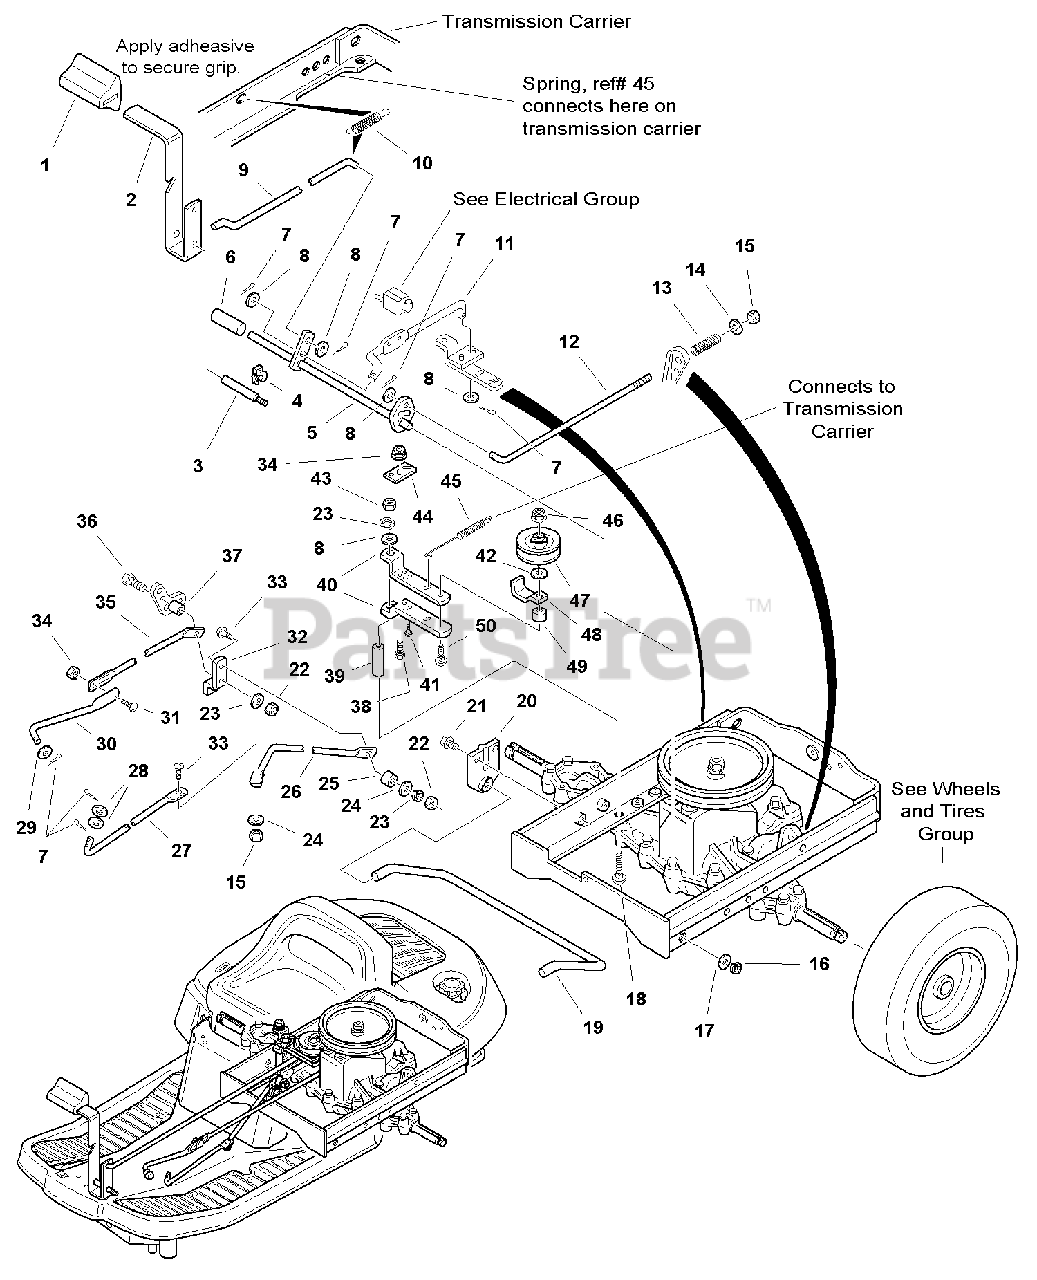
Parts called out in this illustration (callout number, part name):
1	PAD, Pedal
2	LEVER, Clutch
3	PIVOT, Brake
4	KLIP RING, 3/4
5	PIVOT SHAFT ASSEMBLY
7	COTTER PIN, 7/64 x 3/4
9	ROD, Clutch, Front
10	SPRING, Return
11	ROD, Clutch, Rear
13	SPRING, Compression
14	WASHER, 13/32 x 1-1/4 x 5/64
15	NUT, Hex, Lock, 5/16-18
16	KLIPRING, 1/2
17	WASHER, Plain
18	CARRIAGE BOLT, 5/15-18 x 2-3/4
19	TORSION BAR
20	BRACKET, Torsion Bar
21	CAPSCREW Taptite, 5/16-18 x 1/2
22	NUT, Hex Flange Lock, 5/16-18
23	LOCKWASHER, 5/16
24	WASHER, 5/16
26	ROD, Control
27	ROD, Shift, Front
28	WASHER, Plain, 1/2 x 1 x 1/32
29	WASHER, Plain, 13/32 x 7/8 x 5/64
30	ROD, Return, Front
31	CARRIAGE BOLT, 1/4-20 x 7/8
32	LEVER, Control
33	CARRIAGE BOLT, 5/16-18 X 1-1/4
34	NUT, Hex, Flange Whizlock, 1/4-20
35	ROD, Return, Rear
36	CAPSCREW, 5/16-18 x 1-3/4
38	CAPSCREW, Hex Head, 1/4-20 x 3/4
39	SPACER, Pivot
40	CLEVIS, Idler Bracket
41	CAPSCREW, Taptite, 1/4-20 x 5/8
42	WASHER
43	NUT, Hex, 5/16-18
46	NUT, Hex, Jam, Lock, 3/8-16
47	PULLEY, Idler
48	GUARD, Spring
49	SPACER, 25/64 x 5/8 x 11/16
50	CARRIAGE BOLT, 3/8-16 x 2-/1/4
